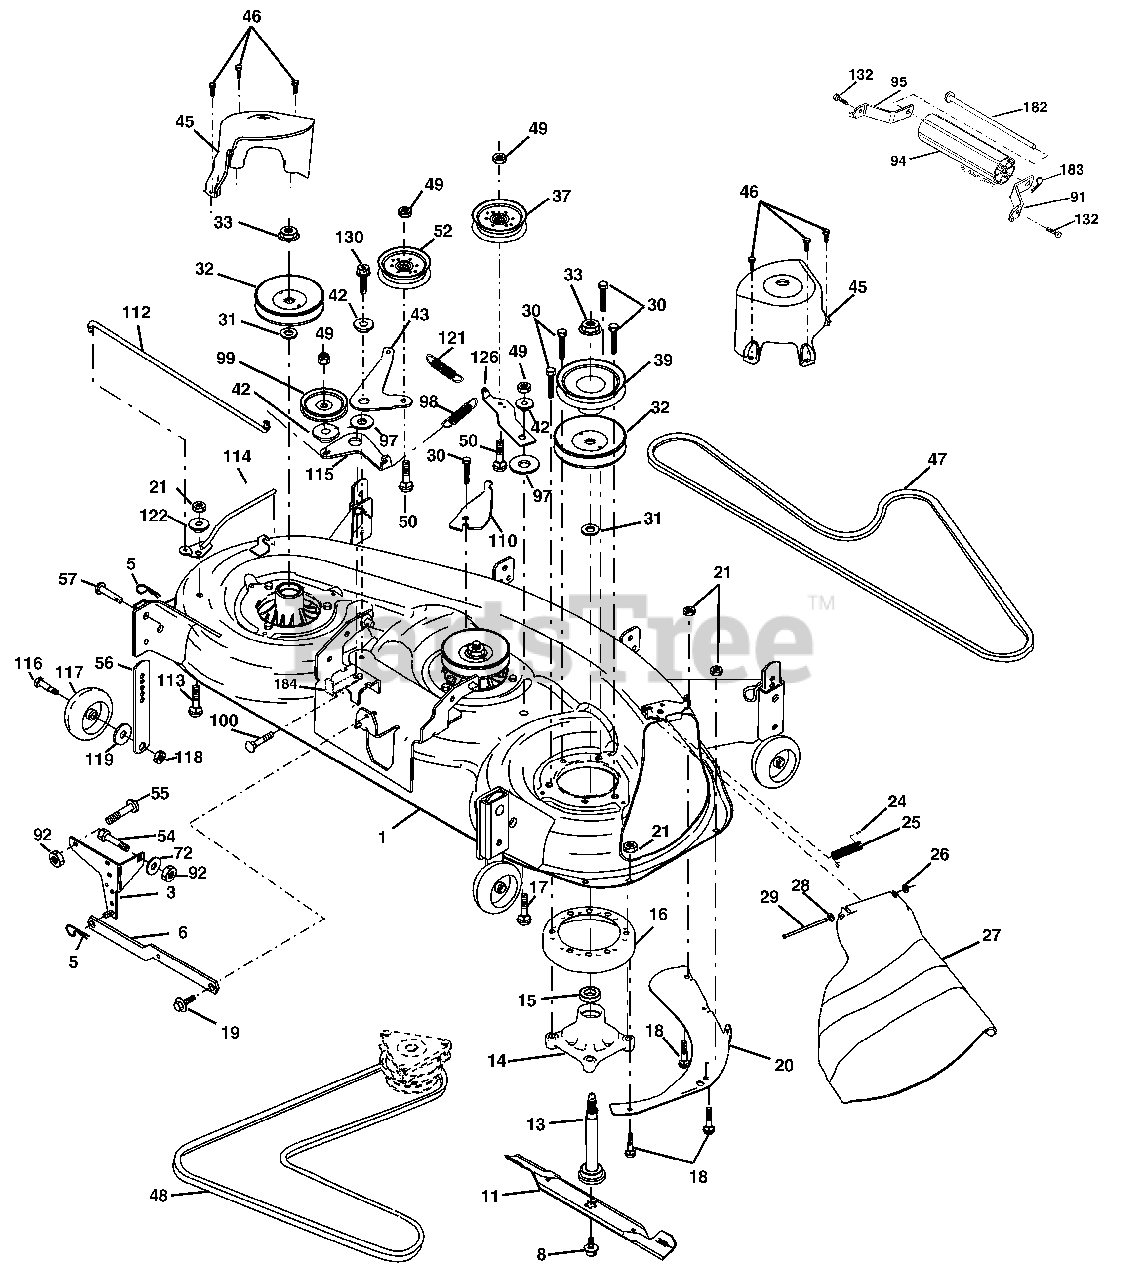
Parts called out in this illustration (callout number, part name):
1	Deck Weldment Mower 48
3	Bracket Asm., Sway Bar
5	Retainer Spring
6	Arm, Suspension, Rear Sway Bar Deck
8	Bolt 7/16 Asm. Blade
11	Blade, 48" Mulching
11	Blade, 48" Hi-Lift
13	Shaft Asm. w/Lower Bearing
14	Mandrel Asm. Housing
15	Bearing, Ball, Mandrel
16	Stripper Mandrel Deck
17	Bolt RDHD Sq Neck 3/8-16 x 1.25
18	Bolt, Carriage 5/16-18 x 5/8
19	Bolt, Hex Hd, Shoulder 5/16-18
20	Baffle, Vortex Mower
21	Nut, Crownlock 5/16-18 unc
24	Cap, Sleeve
25	Spring, Torsion
26	Nut, Push
27	Deflector Shield
28	Washer 11/32 x 5/8 x 16 Ga.
29	Rod, Hinge
30	Screw, Thdroll Washer Head
31	Washer, Spacer
32	Pulley, Mandrel
33	Nut, Flg. Top Lock Cntr. 9/16
36	Washer 13/32 x 13/16 x 16 Ga.
37	Pulley, Idler, Flat
39	Pulley, Idler, Driven
42	Spacer, Retainer
43	Arm, Idler Secondary
45	Cover, Mandrel Deck
46	Screw, Thdroll. 1/4-20 x 5/8
47	V-Belt, Mower, Secondary
48	V-Belt, Mower, Primary
49	Nut, Lock 3/8-16 unc
50	Bolt, Carr. 3/8-16 x 1-1/2 Gr. 5
52	Pulley Idler Flat
54	Bolt Fin Hex 3/8-16 x 1
55	Bolt Carriage Sqnk. 3/8-16 x 1
56	Bar Pnt Adj.
57	Pin Head Rivet
72	Washer 13/32 x 13/16 x 12 Ga.
91	Bracket, Asm Noseroller, RH
92	Nut Lock Hex 3/8-16
94	Noseroller
95	Bracket, Asm Noseroller LH
97	Washer Hardened
98	Spring Primary Drive
99	Pulley Idler "V"
100	Bolt RDHD Sqnk 3/8-16 unc x 2
110	Arm Spring Secondary
112	Link Tension Relief Lever
113	Bolt 5/16-18 x 3/4
114	Tension Asm. Relief Lever
115	Arm Spring Tension Relief
116	Bolt, Shoulder
117	Gauge Wheel
118	Nut, Centerlock 3/8-16 unc
119	Washer 3/8 x 7/8 x 14 Ga.
121	Spring Secondary Drive
122	Bushing Pivot Tension Relief
126	Arm, Idler, Primary Deck
130	Screw 3/8-16 x 1.0
132	Screw 3/8-16 x .75
182	Rod Roller Nose
183	Retainer Spring
184	Keeper Belt Idler
